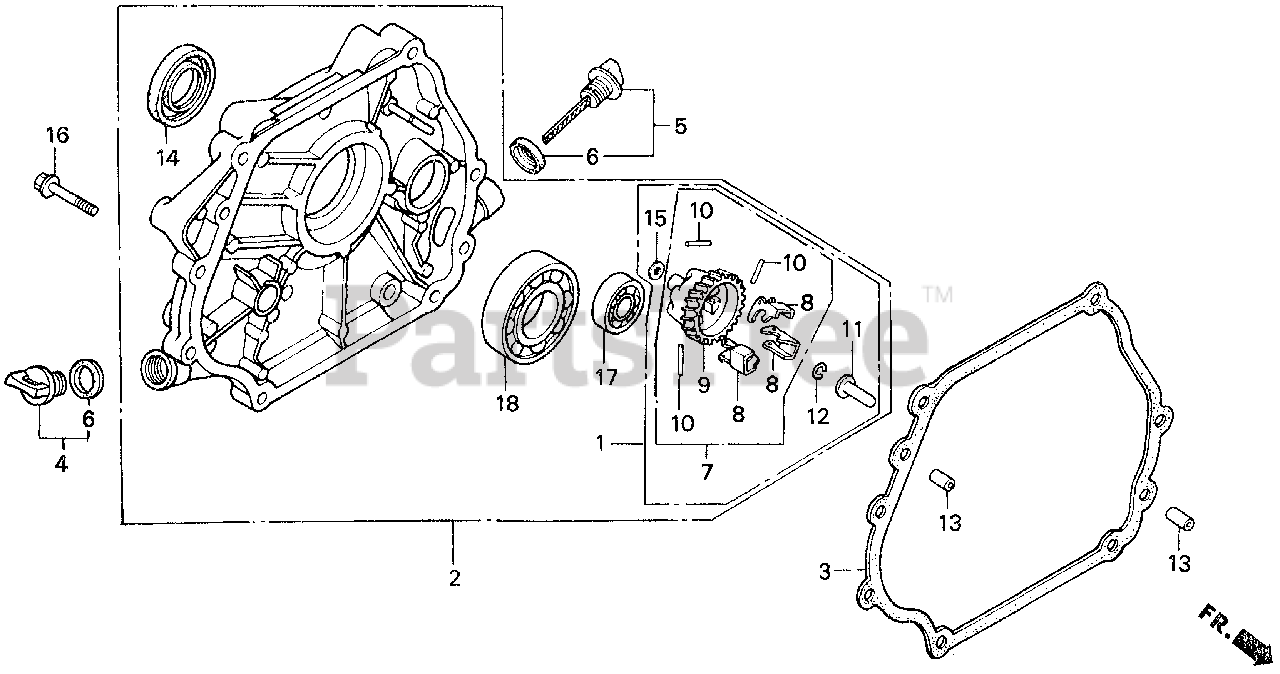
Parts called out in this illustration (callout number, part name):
1	GOVERNOR KIT
2	COVER ASSY., CRANKCASE (S-TYPE)
3	GASKET, CASE COVER
4	CAP ASSY., OIL FILLER
5	CAP ASSY., OIL FILLER
6	GASKET, OIL FILLER CAP
7	GOVERNOR ASSY.
8	WEIGHT, GOVERNOR
9	HOLDER, GOVERNOR WEIGHT
10	PIN, GOVERNOR WEIGHT
11	SLIDER, GOVERNOR
12	CLIP, GOVERNOR HOLDER
13	PIN, DOWEL (8X12)
14	OIL SEAL (35X52X8)
15	WASHER, PLAIN (6MM)
16	BOLT, FLANGE (8X40)
17	BEARING, RADIAL BALL (6202)
18	BEARING, RADIAL BALL (6207)
